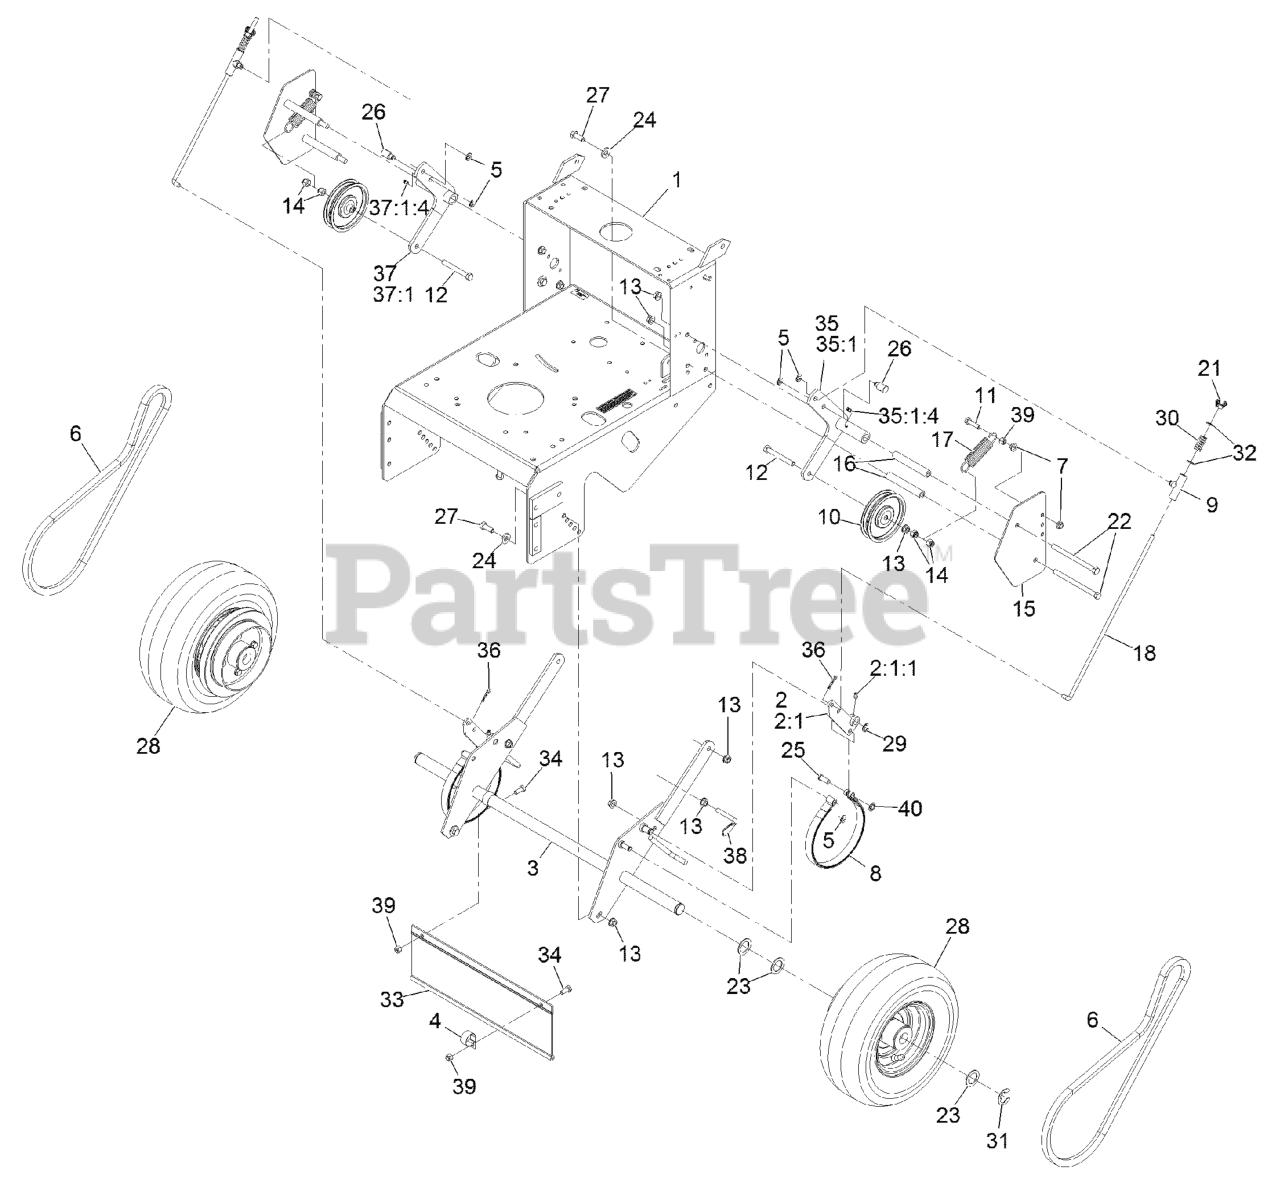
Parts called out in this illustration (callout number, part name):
1	ASM, METRO ENGINE DECK W/
2	ARM-BRAKE
2:1	Wld,Brake Arm
2:1:1	ASM,BUSHING/ZERK
4	CLAMP-R
5	RING-RETAINING
6	BELT-WHEEL, DRIVE
8	BAND-BRAKE
9	SWIVEL-BRAKE
10	IDLER-WHEEL, DRIVE
11	SCREW-HH, SPECIAL
12	SCREW-HH
13	NUT-HHF, WHIZ
14	NUT-LOCK, NI
15	SHIELD-WHEEL, DRIVE
16	SPACER-SHIELD
17	SPRING-EXTENSION
18	LINKAGE-BRAKE
21	WINGNUT-NYLOCK
22	SCREW-HH
23	WASHER-SPACER
24	WASHER-BELLEVILLE
25	PIN-CLEVIS
26	SWIVEL-LEVER, DRIVE
27	SCREW-HH
28	DRIVE WHEEL ASM
29	RING-RETAINING, EXTERNAL
30	SPRING-COMPRESSION
31	RING-SNAP
32	WASHER-PLAIN
33	SHIELD-TRAILING
34	SCREW-HH
35	ARM-IDLER, LH
35:1	Idler Arm LH Assy
35:1:4	FITTING-GREASE
36	PIN-COTTER
37	ARM-IDLER, RH
37:1	Idler Arm RH Assy
37:1:4	FITTING-GREASE
38	SCRAPER
39	NUT-LOCK, NI
40	RING-RETAIN,PUSH,EXT,FLAT
